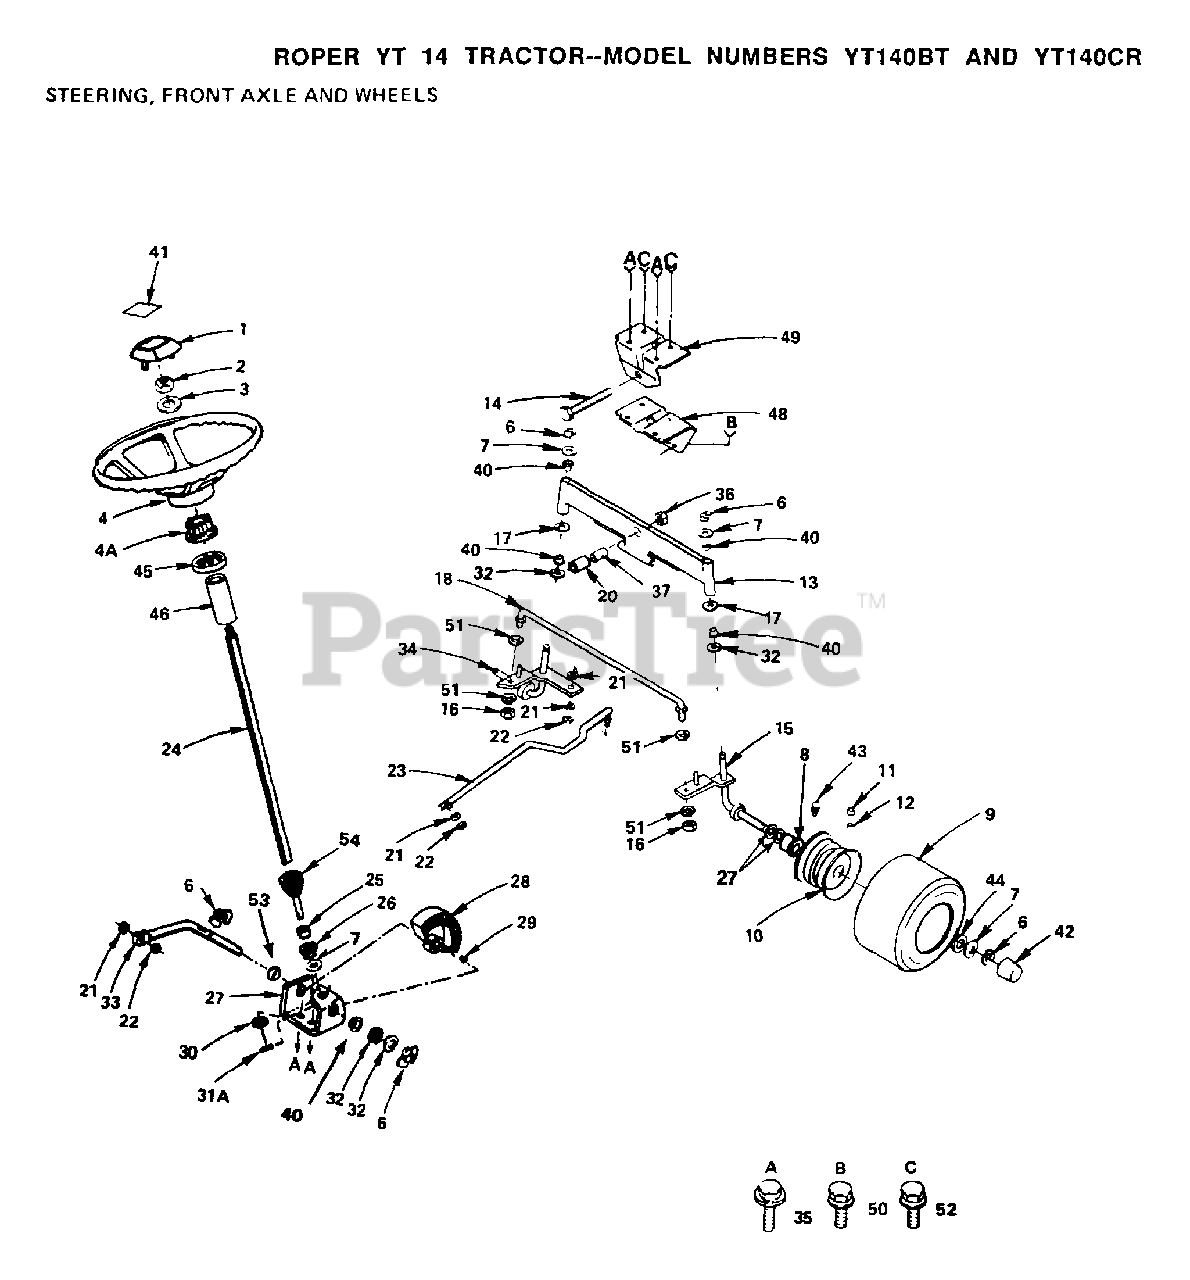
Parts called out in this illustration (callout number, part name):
1	INSERT-WHEEL LT
3	WASHER
4A	ADAPTER LT
5	NYLINER T
6	RING
8	"FLANGE, BEARING"
11	VALVE STEM LT
12	VALVE CAP
13	FRONT AXLE
14	BOLT LT
16	COTTER PIN
19	ZERK M
20	BEARING
21	LOCKWASHER
23	LINK-DRAG LT
25	SHAFT SPACER LT
26	BUSHING
28	GEAR.SECTOR.HYT
29	KEY-WOODRUFF LT
30	WASHER D
32	WASHER .T
33	ROD STEERING T
34	SPINDLE-LH LT
35	SCREW
36	"NUT-LOC,FLANGE LT"
40	COL. SRTG. BEAR.
41	DECAL - STEERING WHEEL
42	HUB CAP
43	FITTING LT
48	SUPPORT.SADDLE.FT
49	SUPPORT-SADDL T
50	SCREW LT
52	WASHER
54	GEAR PINION T
